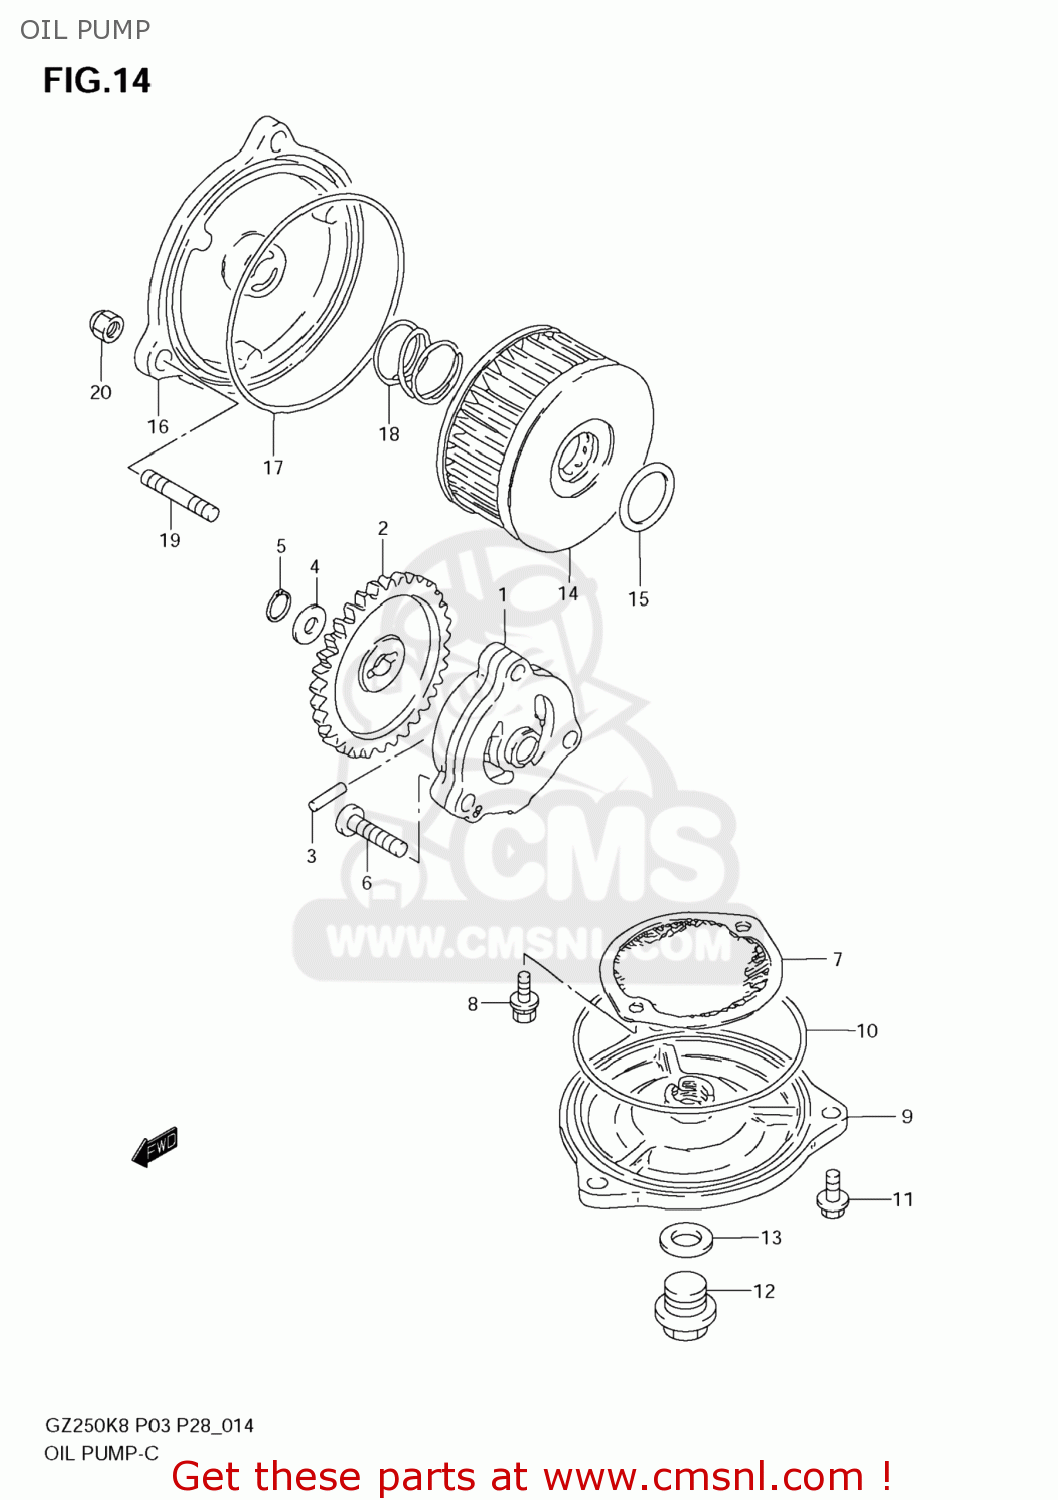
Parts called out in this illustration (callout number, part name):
1	PUMP ASSY,ENGINE OIL
2	GEAR,OIL PUMP DRIVEN(NT:33)
3	PIN(4X15.8)
4	SHIM(10X18X0.5)
5	CIRCLIP,10MM
6	SCREW
7	STRAINER,ENGINE OIL
8	SCREW
9	CAP,OIL STRAINER
10	O RING(D:2.4,ID:85)
11	BOLT
12	PLUG (14X12)
13	GASKET(13.8X18.8X4.8) (NAS)
14	FILTER ASSY,ENGINE OIL
15	O RING(D:2.4,ID:15.8)
16	CAP,OIL FILTER
17	O RING(D:2.4,ID:73)
18	SPRING
19	BOLT,STUD
20	NUT
